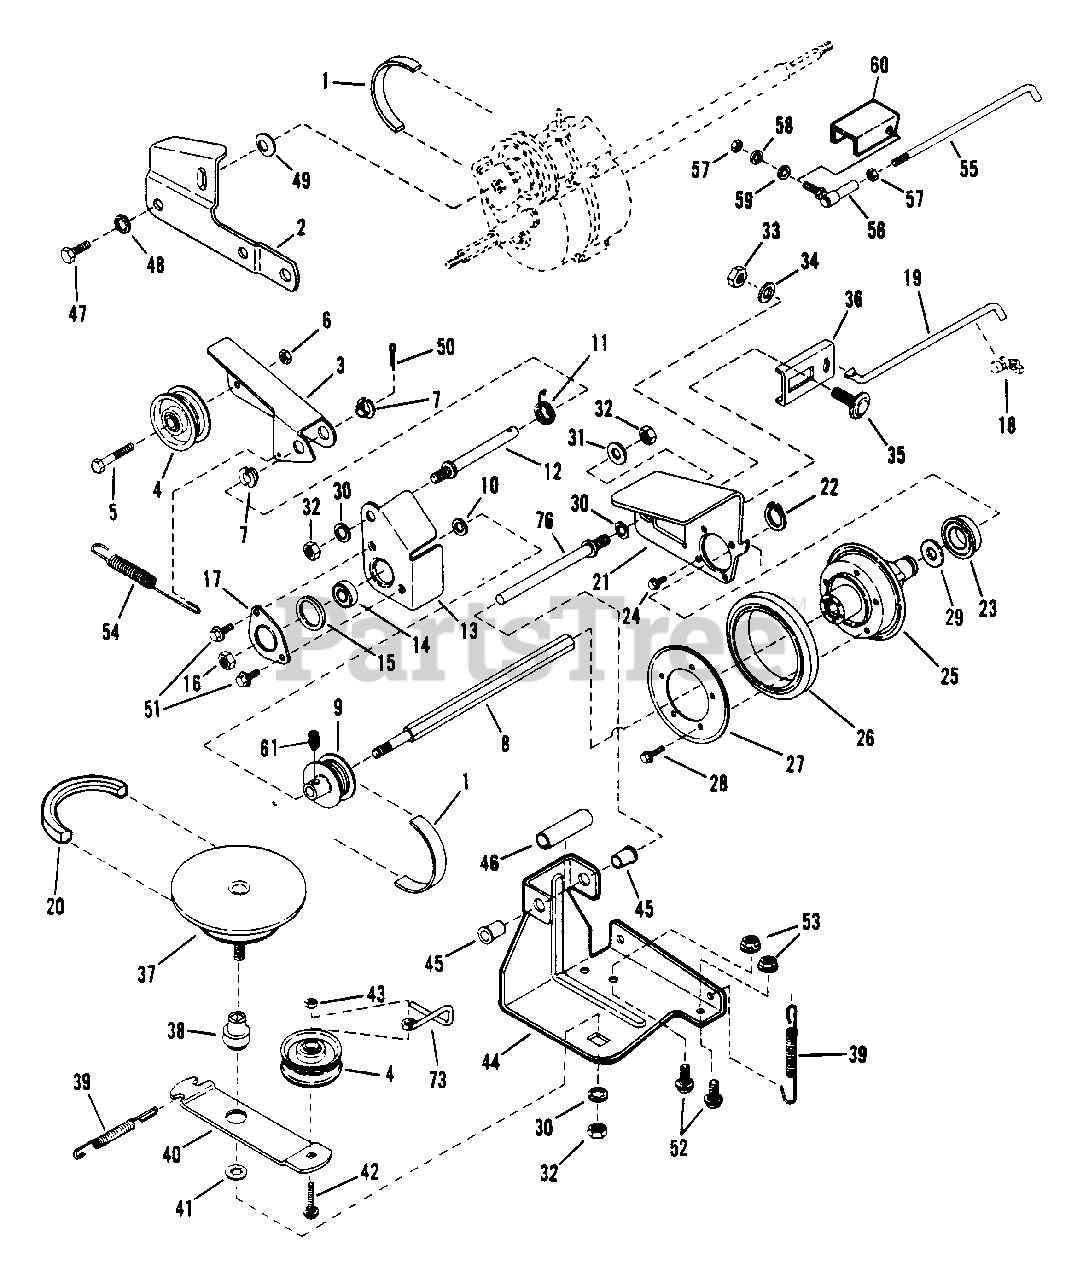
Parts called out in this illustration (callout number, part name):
1	BELT, Poly-Vee
2	LINK, Differential
3	ARM, Clutch Idler
4	PULLEY, Idler
5	SCREW, 1/4-28 x 1-3/8" Hex Head Cap, Grade 5
6	NUT, 1/4-28 Hex Top Lock
7	BUSHING, 3/8 I.D. Nylon
8	SHAFT, Hex Drive
9	PULLEY, Poly-V (2" O.D.)
10	WASHER, 3/8" Flat
11	SPRING, Torsion
12	STUD
13	HOLDER, Bearing (Inner Half)
14	BEARING, Ball
15	0-RING
16	NUT, 3/8-24 Hex Center Lock, Grade 5
17	HOLDER, Bearing (Outer Half)
18	CLIP, 1/4 Right Arc (Transfer Rod)
19	ROD, Transfer
20	BELT, Engine Drive
21	PLATE, Thrust
22	RING, Retaining
23	BEARING, Ball
24	SCREW, #10-32 x 1/4" Self-Tapping Machine
25	ASSEMBLY, Hub (Includes 11108 Bushing & 90913 Screws)
26	RING, Driven
27	PLATE, Ring Retaining
28	SCREW, #10-24 x 1/2" Hex Washer Self-Tap (Torx)
29	WASHER, 3/4 Shim
30	WASHER, 3/8 Internal Tooth Lock
31	WASHER, 3/8" Flat
32	NUT, 3/8-24 Hex, Grade B
33	NUT, 5/16-18 Hex, Grade 5
34	WASHER, 5/16 Split Lock
35	BOLT, 5/16-18 x 3/4" Carriage, Grade 5
36	CONNECTOR, Transfer Rod
37	KIT, Drive Disc Assembly
38	BUSHING
39	SPRING (Wheel Drive & Idler)
40	ARM, Idler
41	RETAINER, 3/8 Bolt
42	BOLT, 1/4-20 x 1-1/2" Carriage, Grade 5
43	NUT, 1/4-20 Hex Center Lock, Grade 5 or B
44	BRACKET, Deck
45	BUSHING, Flange
46	SPACER
47	SCREW, 5/16-18 x 1/2" Hex Head Cap, Grade 5
48	WASHER, 5/16 Internal Tooth Lock
49	WASHER, Spring
50	PIN, 3/32 x 1/2" Cotter
51	SCREW, 1/4-20 x 1/2" Self-Tapping
52	BOLT, 5/16-18 x 1/2" Short Neck Carriage, Grade 5
53	NUT, 5/16-18 Hex Flange Lock, Grade 5
54	SPRING, Clutch
55	**LINK, Transfer
56	**JOINT, Ball
57	**NUT, 1/4-28 Hex, Grade 5
58	**WASHER, 1/4 Flat
59	**WASHER, 1/4 Internal Tooth Lock
60	SHIELD, Hex Shaft
61	*SCREW, 1/4-28 x 1/4" Hex Socket Set
73	*SCRAPER, Drive Pulley
76	GUIDE, Thrust Plate
